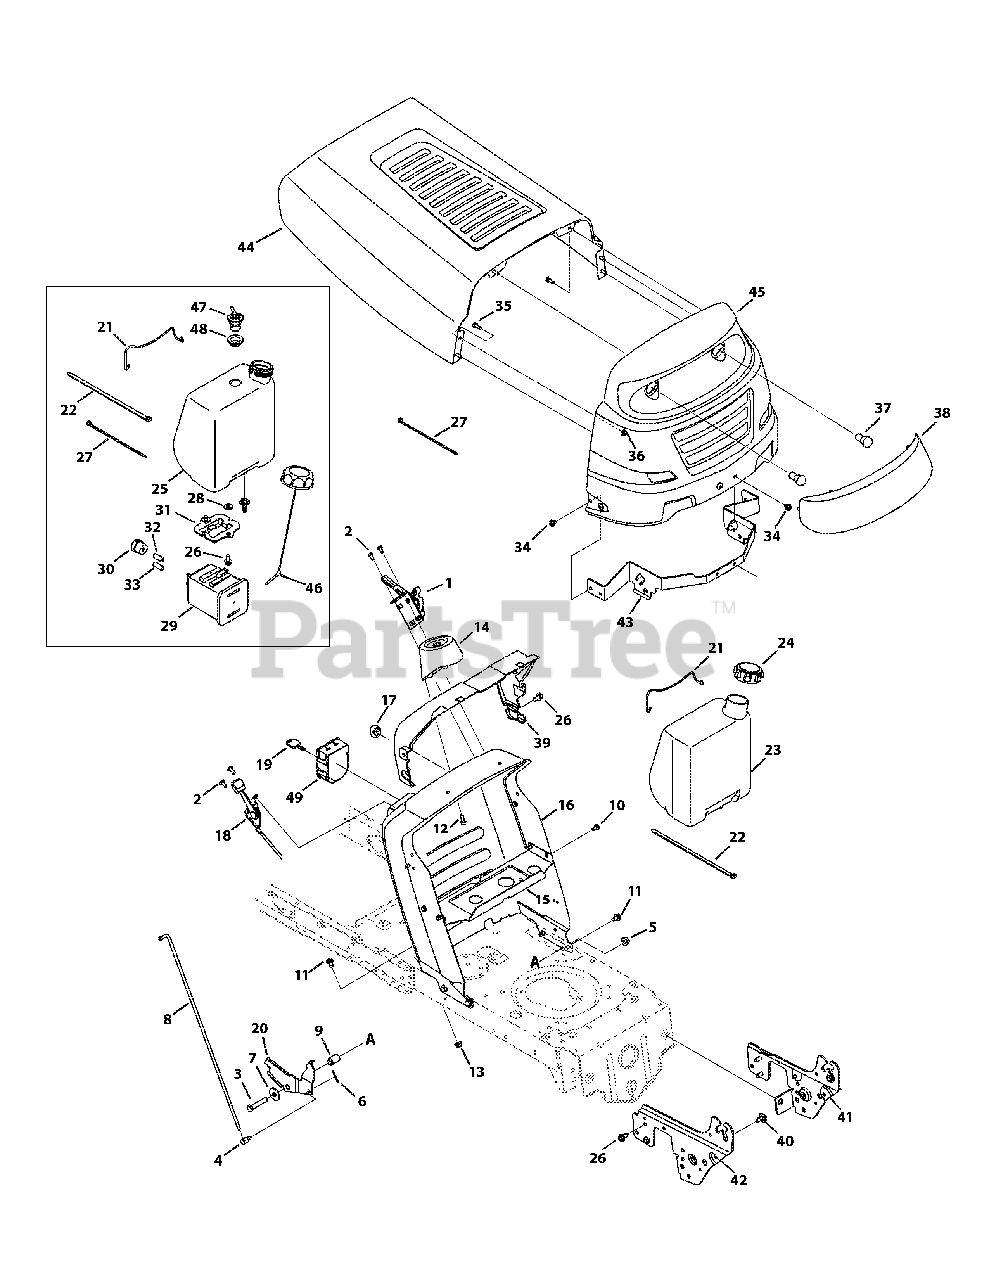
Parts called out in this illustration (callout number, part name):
1	7-Speed Control Assembly
1	6-Speed Control Assembly
2	Screw, 1/4-20 x .500
3	Hex Screw, 3/8-16 x 2.0
4	Ferrule, 1/4-20 x 1.00
5	Flangelock Nut, 3/8-16
6	Cotter Pin, 3/32 x 1.0
7	Flat Washer, .411 x 1.25 x .100
8	Speed Selector
9	Flange Spacer, .390 x .671 x 1.095
10	Hex Washer Screw, 1/4-20 x .500
11	Screw, 5/16-18 x .625
12	Screw, 1/4-15 x .750
13	Flangelock Nut, 5/16-18
14	Steering Support
15	Gas Tank Support Bracket
16	Dash, No RMC - Powder Black
16	Dash, No RMC - Black Jack
16	Dash, No RMC - Green
17	Choke Plug
18	Throttle/Choke Cable
21	Battery Assembly Rod
22	Cable Tie
23	1.5 Gallon Fuel Tank
24	Fuel Cap
25	1.36 Gallon Fuel Tank
26	Screw, 5/16-18 x .750
27	Cable Tie
28	Flat Washer, .344 x .750 x .120
29	5 Gallon Carbon Canister
30	Vent Filter Canister
31	Canister Adapter
32	Fuel Hose, White
33	Fuel Hose, Yellow
34	Screw, 5/16-18 x .375
35	Hex Screw, 1/4-20 x .620
36	Flangelock Nut, 1/4-20
37	Miniature Lamp 12V Socket
38	Lens Grill
40	Shoulder Screw, 5/16-18 x .43 x .29
41	Left Support Pivot Bracket
42	Right Support Pivot Bracket
43	Hood Pivot Bracket
44	Hood - Red
44	Hood - Yellow
44	Hood - Gray
44	Hood - Green
45	Grill - Red
45	Grill - Yellow
45	Grill - Gray
45	Grill - Green
46	Fuel Cap, 2.25"
47	Rollover Valve
48	Rubber Grommet, 23 x 3.55
49	Key Switch
